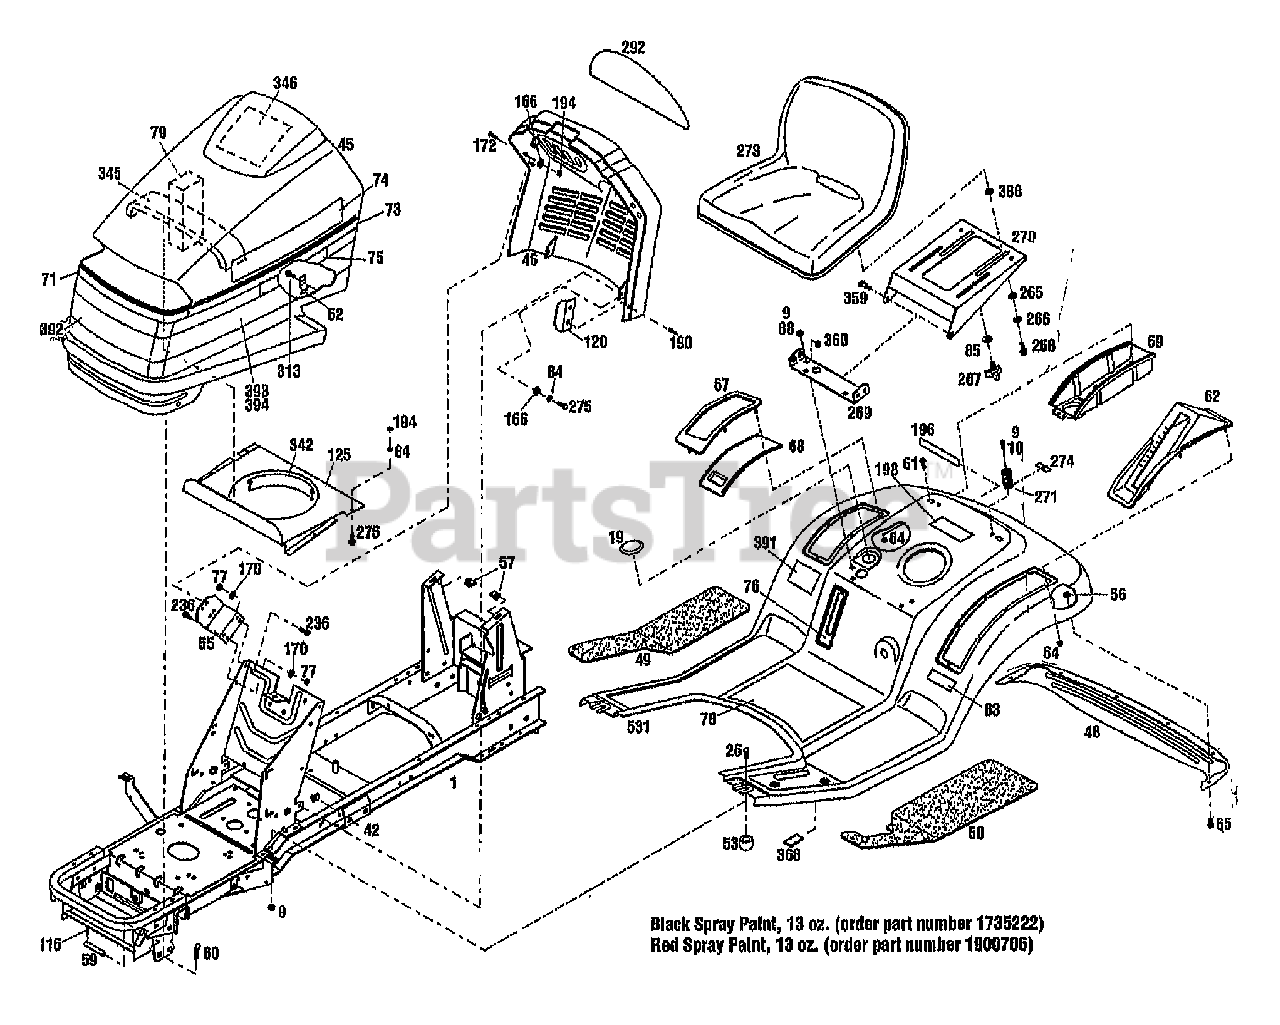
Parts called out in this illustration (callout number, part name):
1	ASSM-FRAME {13078}
1	ASSM-FRAME LTX {13079}
9	NUT-HFLK 5/16-18 ZP
10	SCR-HHC 5/16-18X.75 GR 5 ZP
19	PLUG 2.50 {13079}
26	SCR-CARR 5/16-18X1.0 G2 ZP
42	NUT-SPEED
45	HOOD-TRACTOR
46	CONSOLE
49	PAD-FOOT RH
50	PAD-FOOT LH
52	LATCH
53	SPACER-TUBULAR
55	BRKT-MOUNTING
56	NUT-HF/LK 1/4-20 ZP
57	NUT-SELF RETAIN 5/16-18
59	PIN-PIVOT HOOD
60	PIN-HITCH .125X2.56 ZP
61	SCR-LOCK
62	COVER-LIFT HANDLE
63	DECAL-AMERICAN LEGEND-LRG
64	NUT-SELF THREADING
65	SCR-HH 1/4-20X.625
67	TOP-STORAGE COVER
68	COVER-CONTAINER
69	CONTAINER-STORAGE
71	DECAL-STRIPE HOOD FRONT
73	DECAL-STRIPE SIDE
74	DECAL-LOGO TROY-BILT
75	DECAL-MODEL 13039 {13078}
75	DECAL-MODEL 13036 {13079}
76	DECAL-FUEL LEVEL
77	NUT-HEX 5/16-18 ZP
78	DECAL-OPER INST
79	BLOCK-SEALING {13078}
84	WASHER-LK .25 ZP
85	WASHER-FLAT 3/8 SAE
88	SCR-CARR 5/16-18X.62 G2 ZP
115	PIN-ROLL .188X1.0
120	BRKT-HOOD ALIGN
125	SHIELD-HEAT UPPER
166	WASHER-FLAT 1.25X.28X.062 ZP
170	WASHER-LK .312 ZP
190	RIVET-POP
194	NUT-HEX 1/4-20 ZP
196	DECAL-LOGO FENDER
198	DECAL-FUEL
236	SCR-HFLK 5/16-18X.75 ZP
265	WASHER-1.06X.51X.09 NYLON
266	WASHER-BOW .74X.52X.01
268	SCR-SHLDR 3/8-16X.25 G5ZP
269	BRKT-SUPPORT SEAT
270	SUPPORT-SEAT
271	SPRING-COMPRESSION
274	BRKT-SPRING HOLD DOWN
275	SCR-HH 1/4-20X.625 G5 ZP
292	LENS-INSTRMTS WARN LIGHTS
342	GASKET-HEAT SHIELD
345	STRIP-SEALING
346	DECAL-SERVICE
359	SCR-HH 3/8-16X.88 G5 ZP
360	NUT-H/LK 3/8-16
388	WASHER-FLAT
391	DECAL-LOGO WORLD CUP
392	DECAL-LOGO WORLD CUP FRONT
393	DECAL-LOGO WORLD CUP LH
394	DECAL-LOGO WORLD CUP RH
531	FENDER-RED W/DECALS
